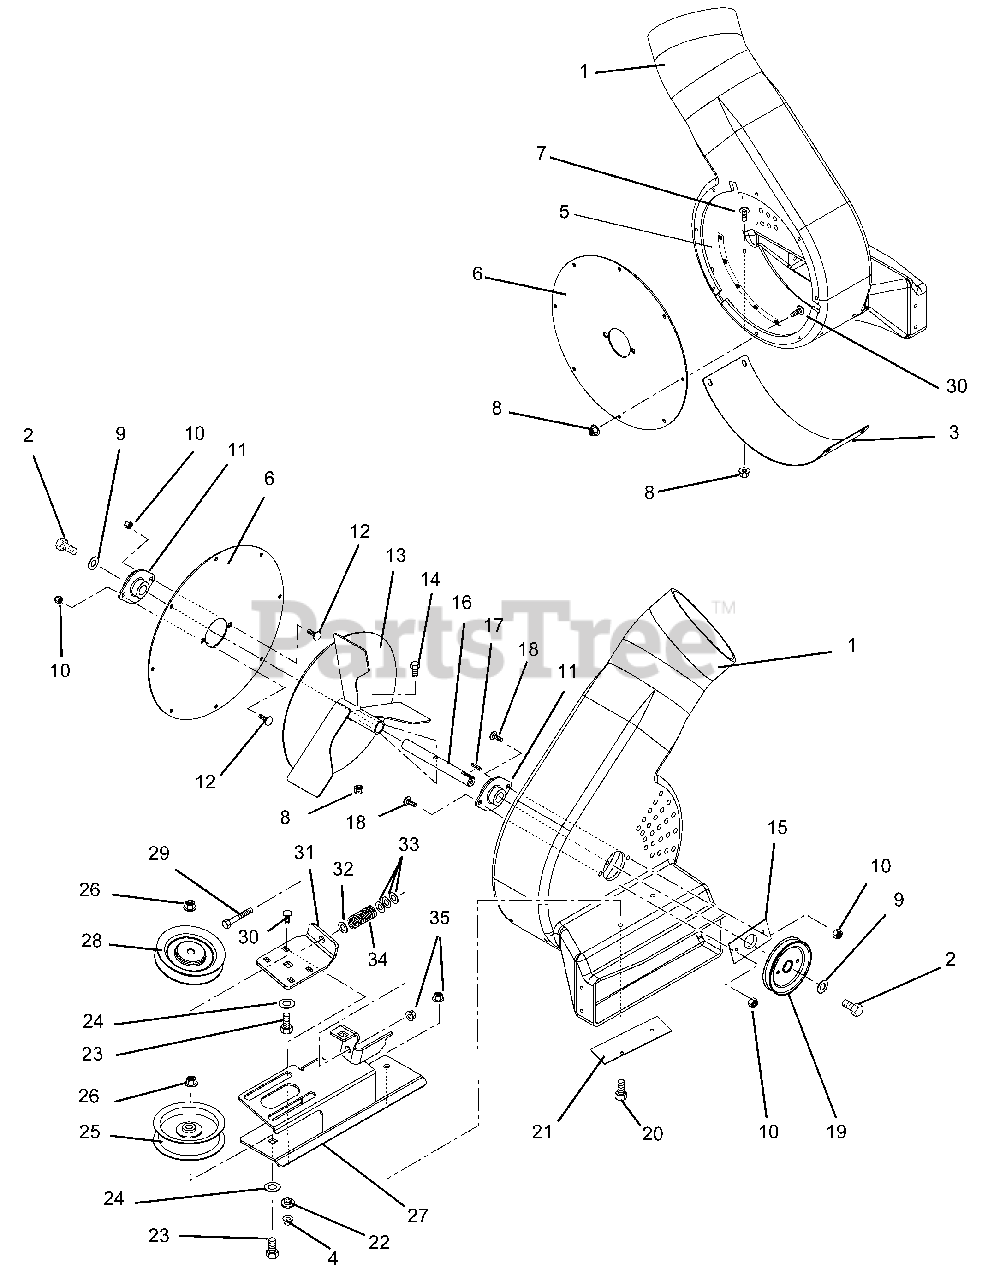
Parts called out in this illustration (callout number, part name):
1	Housing, Blower
2	Bolt, Hex .25-20 x .50
3	Plate, Skid
4	Nut-Locking-Top-Flange .25-20
5	Plate, Mounting Bolt Reinforcing
6	Plate, Bearing Mount
7	Screw-Machine .25-20 x .75
8	Nut, .25-20 Nyloc Flange
9	Washer-Flat-Steel .344 x 1.125 x .135
10	Nut-Nyloc Flange .312-18
11	Bearing, 2 Bolt Flange - .75 ID
12	Bolt-Round Head Square Neck .31-18 x .75
13	Weldment, Impeller, 3 Blade
14	Bolt-Hex .25-20 x 1.50 Grade 8
15	Plate, Washer Bearing
16	Shaft, Impeller
17	Key-Square .187 x .50 x .187 Hardened
18	Bolt-Round Head Square Neck .31-18 x 1.00 Grade 5
19	Sheave, Blower- 4.25 Diameter
20	Bolt-Hex .31-18 x .875 Grade 5
21	Plate, Back
22	Bushing-Flange .265 x .437 x .250 x .750
23	Bolt-Hex .38-16 x 1.75 Grade 5
24	Washer-Flat-Steel .406 x .812 x .065
25	Idler Flanged 3.50
26	Nut-Locking-Top-Flange .38-16
27	Weldment, Idler Mount
28	V-Idler, 4.00 x .38
29	Bolt-Hex .31-18 x 4.00 Grade 5
30	Bolt-Round Head Square Neck .25-20 x .75 Grade 5
31	Bracket, Adjustable Idler
32	Nut-Push .312
33	Washer-Flat-Steel .406 x 1.00 x .188
34	Spring-Compression .092 x .77 x 3.13
35	Nut-Locking-Top-Flange .31-18
36	Blower, Service Assembly (includes items 1-35)
